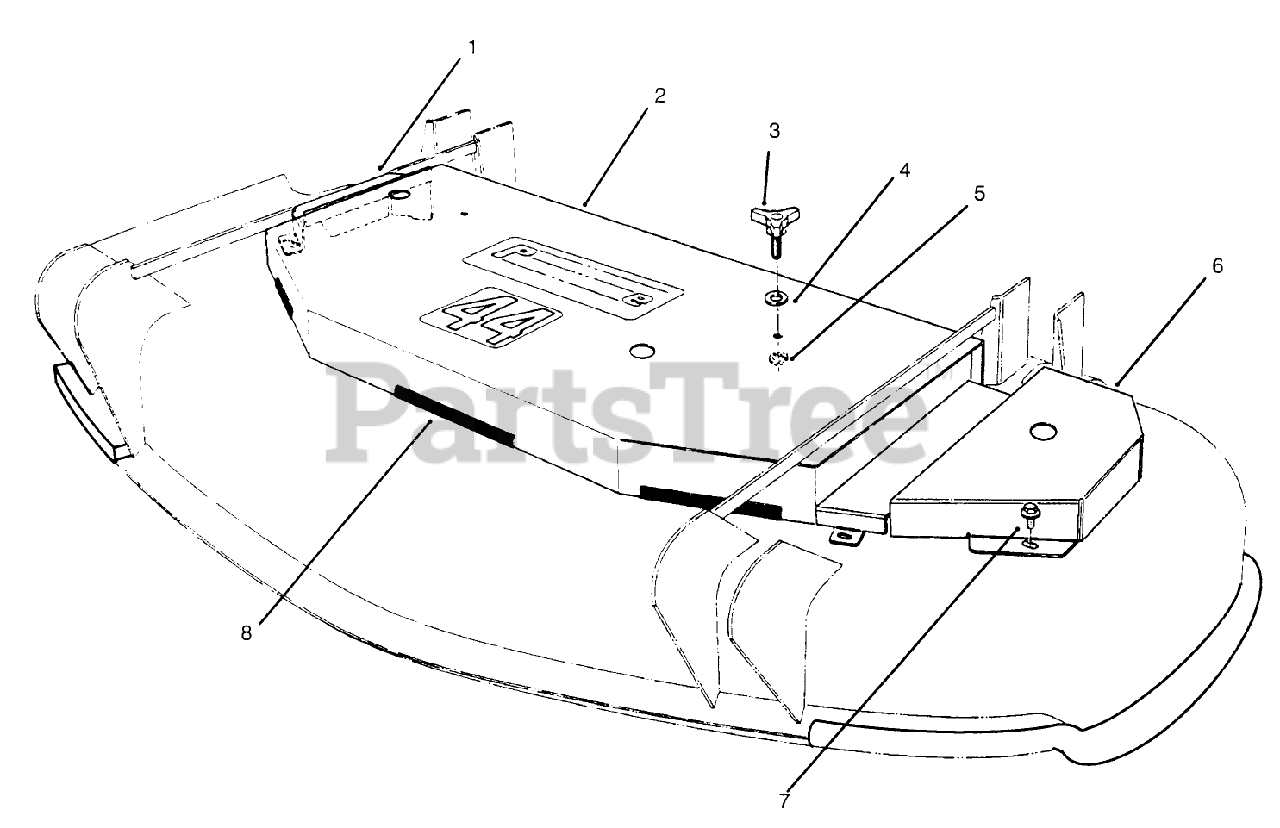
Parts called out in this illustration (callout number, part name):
1	Cover-RH
2	Cover-Deck
4	WASHER-FLAT
5	RING-RETAINING
6	Cover-LH
7	SCREW-HHFTF
8	TRIM-JIFFY
